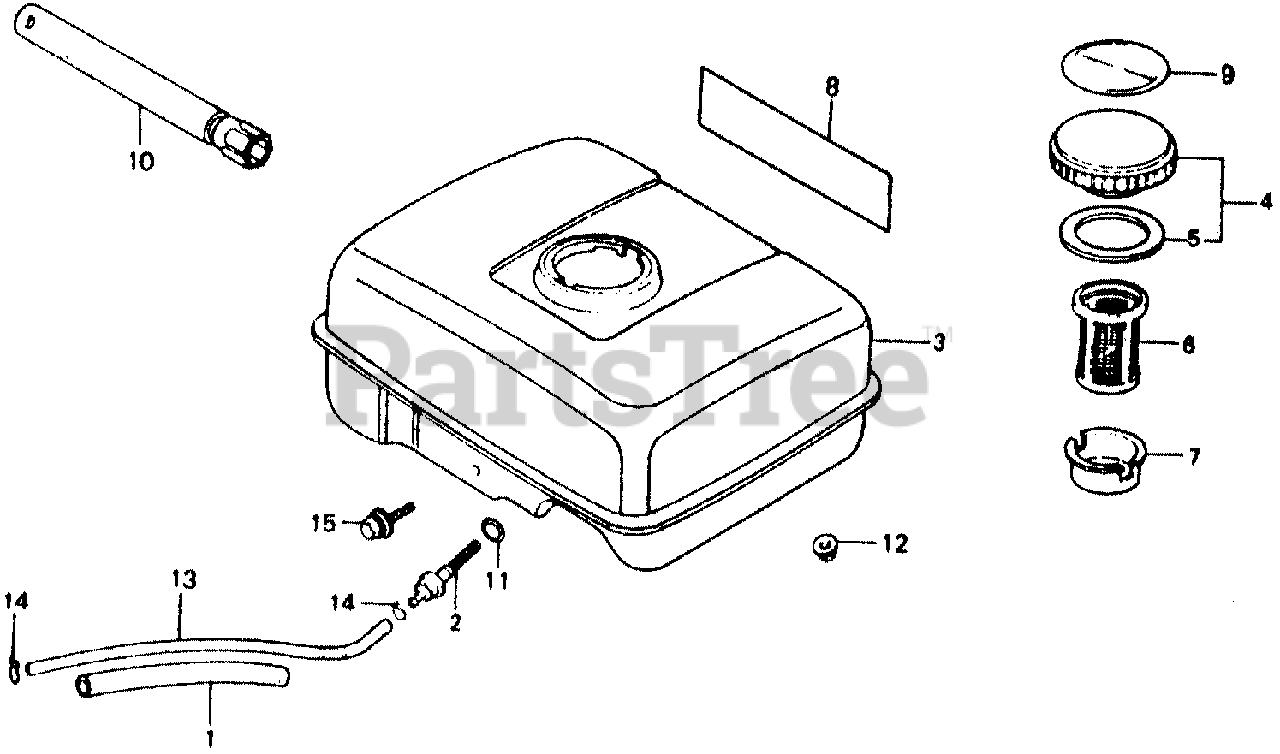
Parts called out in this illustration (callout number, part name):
1	RUBBER, SUPPORTER (107MM)
2	JOINT, FUEL TANK
3	TANK, FUEL *NH31* (MCKINLEY WHITE)
4	CAP, FUEL FILLER
5	GASKET, FUEL FILLER CAP
6	FILTER, FUEL
7	HOLDER, FUEL FILTER
8	MARK (WT20X)
9	MARK, CAUTION (EXTERNAL)
10	WRENCH, SPARK PLUG
11	O-RING (13.5X1.5) (ARAI)
12	NUT, FLANGE (6MM)
13	BULK HOSE, FUEL (4.5X3000) (4.5X140)
14	CLIP, TUBE (B8)
15	BOLT, FLANGE (6X25)
